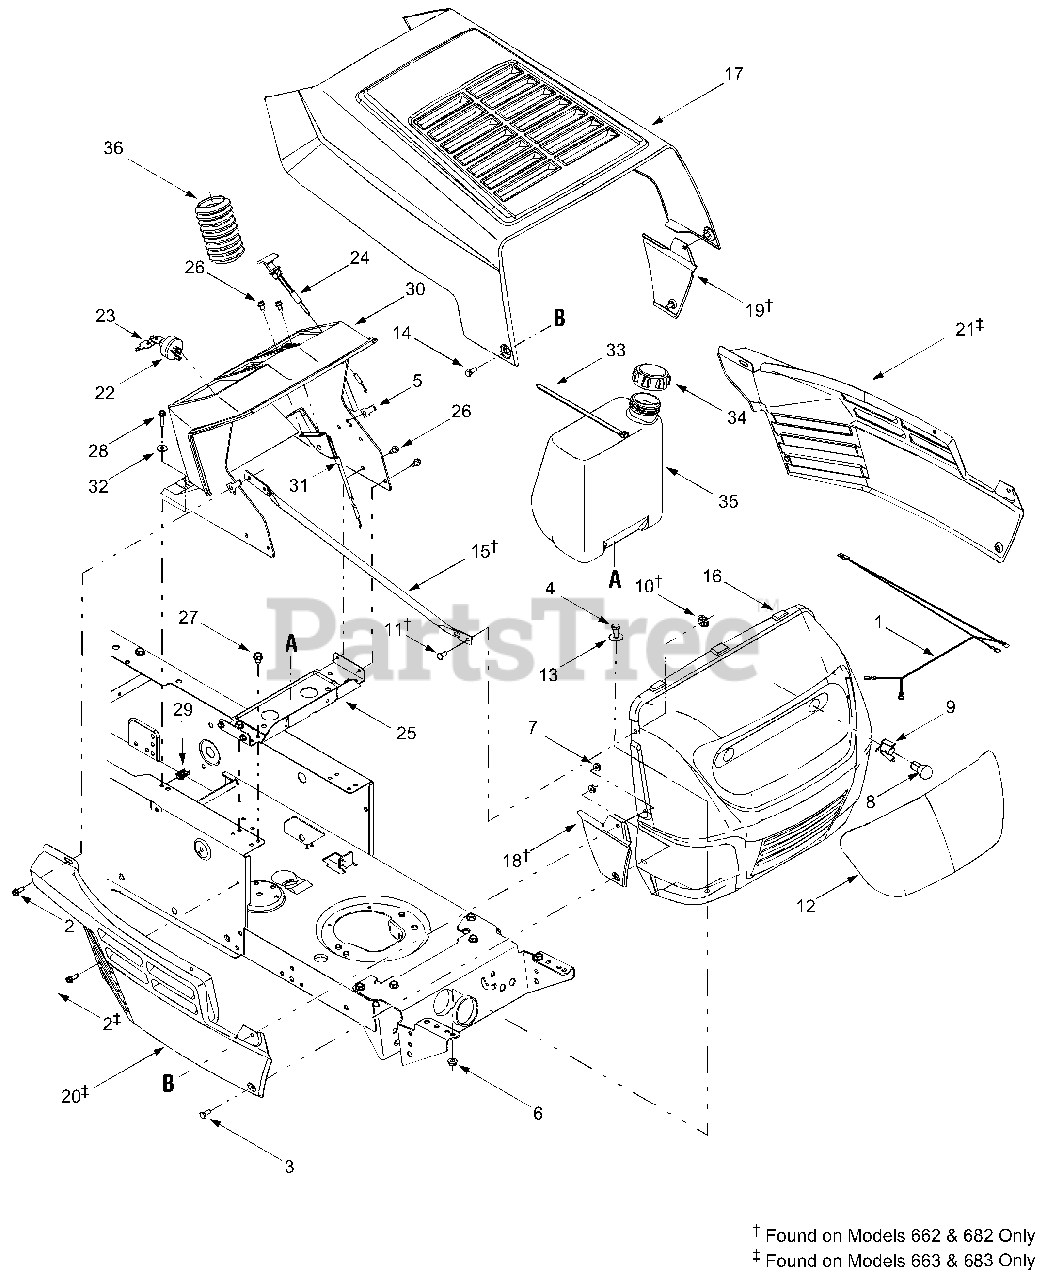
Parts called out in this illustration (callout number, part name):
1	Headlamp Harness Assembly
2	Self-tapping Screw, 1/4-20 x .75
3	Hex Screw, 1/4-20 x .620
4	Hex Screw, 5/16-18 x .75
5	U-type Speed Nut, 1/4-20
6	Lock Nut, 5/16-18
7	Lock Nut, 1/4-20
8	Headlamp, 12V
9	Headlamp Socket
10	Push-on Nut, .25
11	Flat-head Rivet, 1/4
12	Lens
13	Flat Washer, .344 x 1.0 x .063
14	Shoulder Screw, 1/4-20 x .375 /.125
23	Keys (pair)
24	Choke Control, 38"
24	Choke Control, 23"
27	Self-tapping Screw, 5/16-18 x .5
28	Self-tapping Screw, 1/4-20 x 1.0
29	U-type Speed Nut, 1/4-20
30	Dash Panel (models w/o choke knob)
30	Dash Panel (models w/ choke knob)
31	Throttle / Choke Control, 18.5"
31	Throttle Control, 35.5"
31	Throttle Control, 18.5"
32	Flat Washer, .260 x .720 x .060
33	Cable Tie, 30.66
34	Fuel Tank Cap
35	Fuel Tank, 1.5 gal.
36	Steering Bellow, 4.75"
